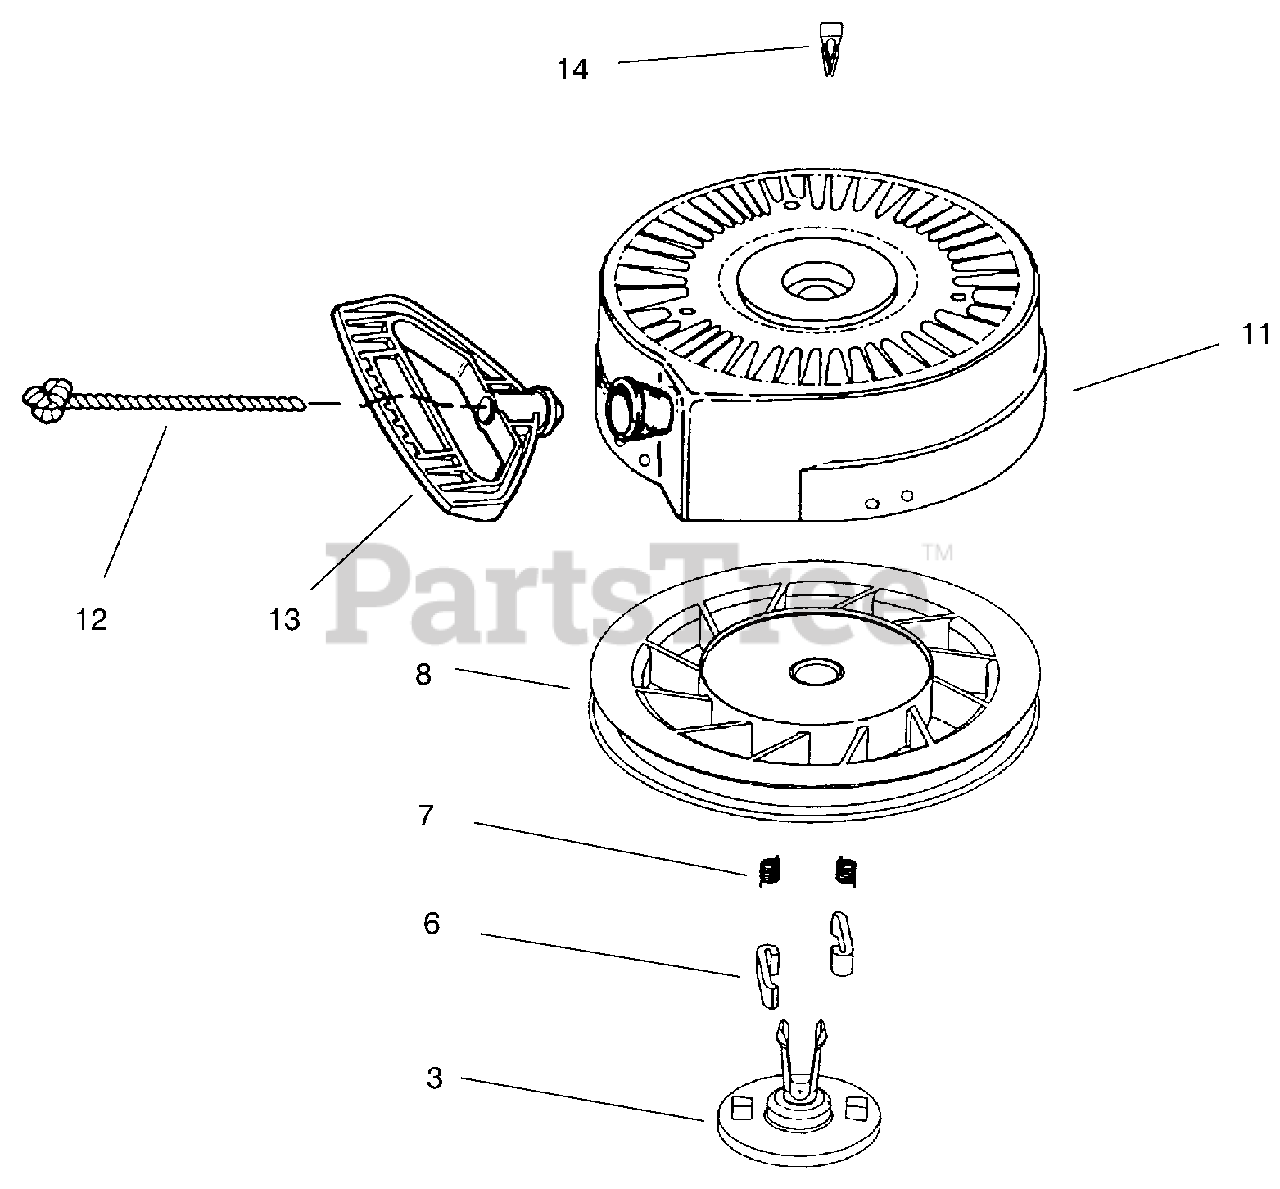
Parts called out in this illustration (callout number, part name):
3	Retainer
6	Dog-Starter
7	Dog Spring
11	Housing Assembly
12	Rope Starter
13	Handle-Starter
14	Locking Tab
